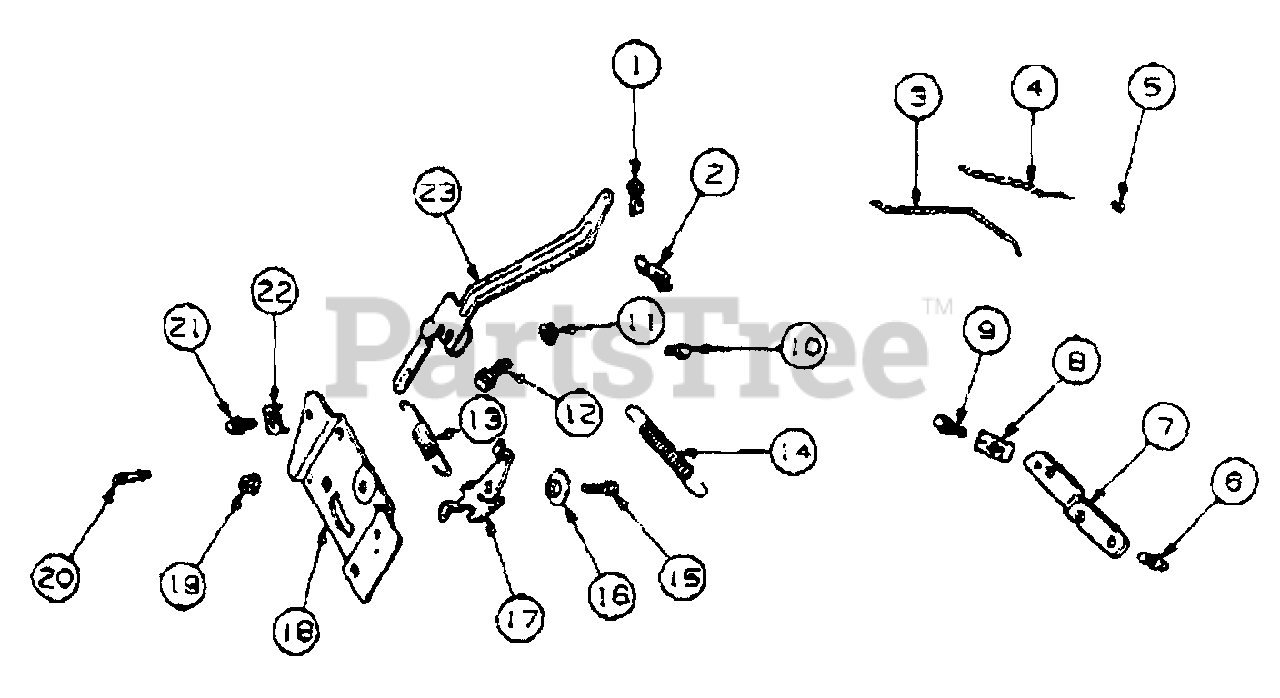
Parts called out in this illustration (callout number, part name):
1	Bushing, Throttle
2	Lever, Choke, Upper
3	Linkage, Choke, Upper
4	Linkage, Throttle
5	Bushing, Linkage
6	Screw, Bracket, M5 x .8 x 10
7	Bracket, Choke Mount
8	Clamp, Cable
9	Screw, Clamp, M5 x .8 x 16
10	Screw, M5 x .8 x 10
11	Nut, M6 x 1
12	Screw, Gov Arm, M6 x 1 x 25
13	Spring, Governor
14	Spring, Linkage
15	Screw, Throttle Control, M5 x .8 x 16
16	Spacer, Throttle Control
17	Lever, Throttle Control
18	Plate, Control
19	Nut, Hex, M5 x .8
20	Screw, Control Plate, M6 x 1 x 16
21	Screw, Cable Clamp, M5 x .8 x 16
22	Clamp, Cable
23	Lever, Governor
